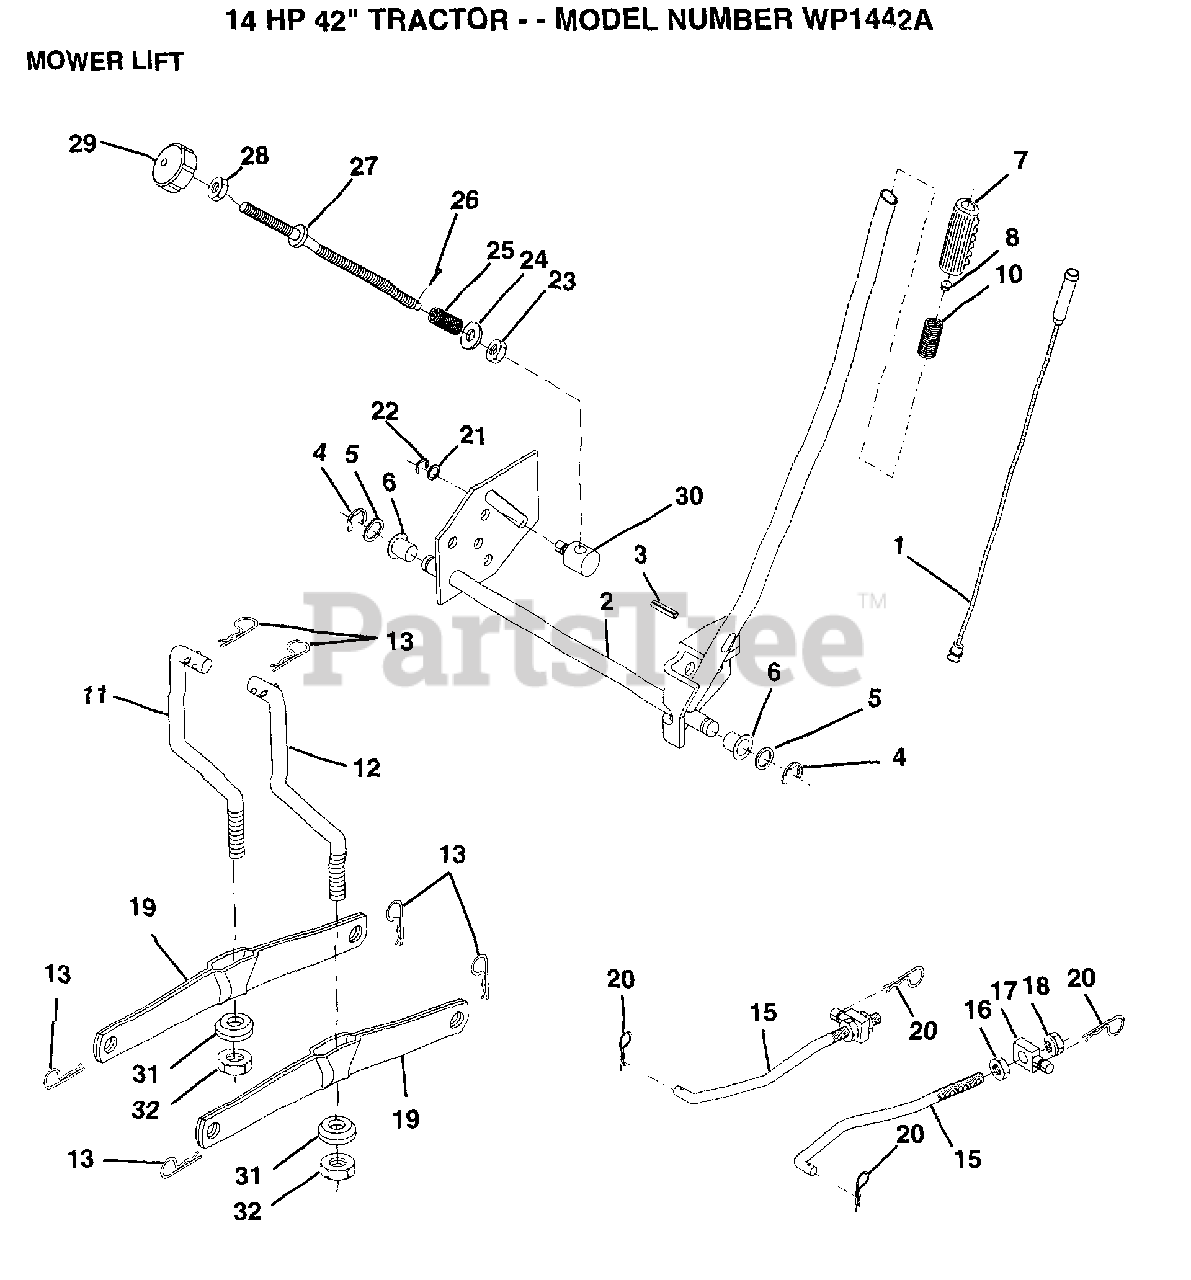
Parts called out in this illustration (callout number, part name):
1	WIRE.ASM.INNER
2	SHAFT.ASM.LIFT.RH
3	PIN GROOVE
5	WASHER
6	NYLON BEARING
7	GRIP
15	LINK.FRONT
16	NUT
17	TRUNION
18	NUT.LK.W/WSH.1/2.
19	ARM SUSP REAR
20	RETAINER.SPRING
21	WASHER
22	KLIP RING
23	NUT T
24	WASHER
25	SPRING T
27	ROD LIFT LT
28	NUT
29	KNOB INF 3/8-16
30	TRUNION LT
31	BEARING PVT LH
32	NUT.LOCK.3/8-24
